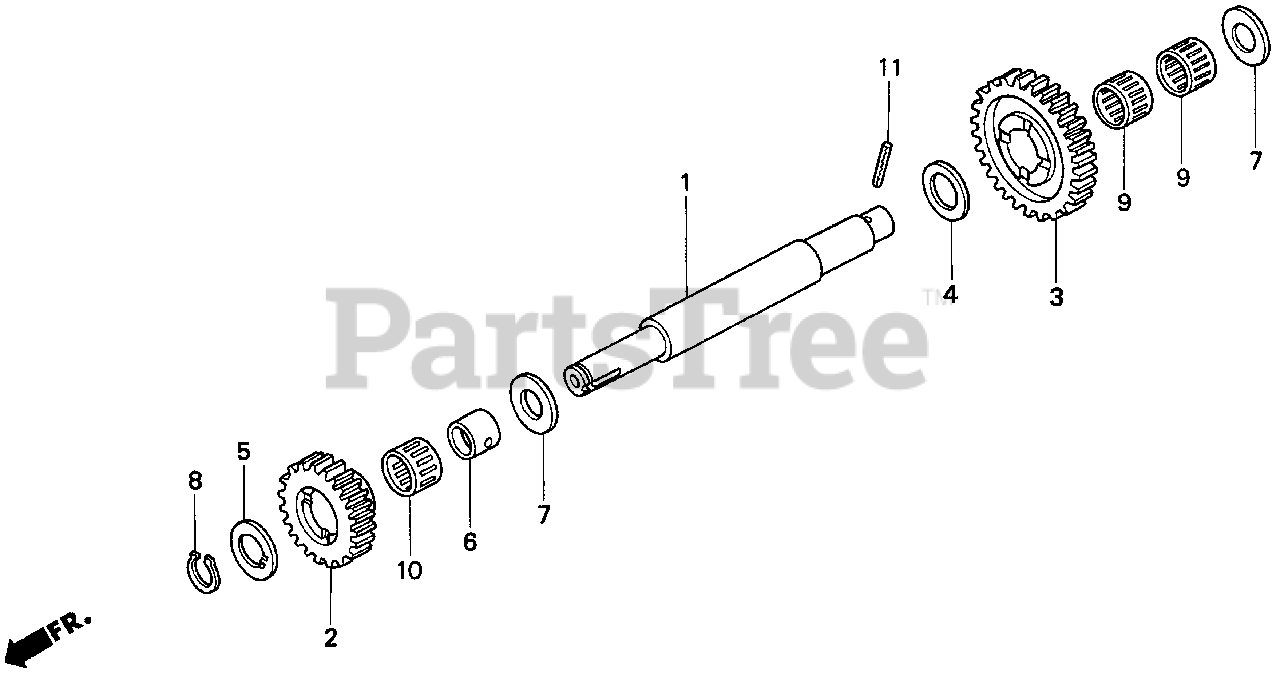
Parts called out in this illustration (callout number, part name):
1	SHAFT, AUXILIARY IDLE
2	GEAR B, AUXILIARY LOW IDLE
3	GEAR, FR. IDLE (28/13T)
4	WASHER, THRUST (20X31.5)
5	WASHER, THRUST (17X32X2)
6	COLLAR (17X21X17)
7	WASHER, THRUST (17X31X2)
8	CIRCLIP (OUTER) (17MM)
9	BEARING, NEEDLE (20X24X13) (NTN CORP.)
10	BEARING, NEEDLE (21X25X17)
11	PIN, SPRING (4X25)
